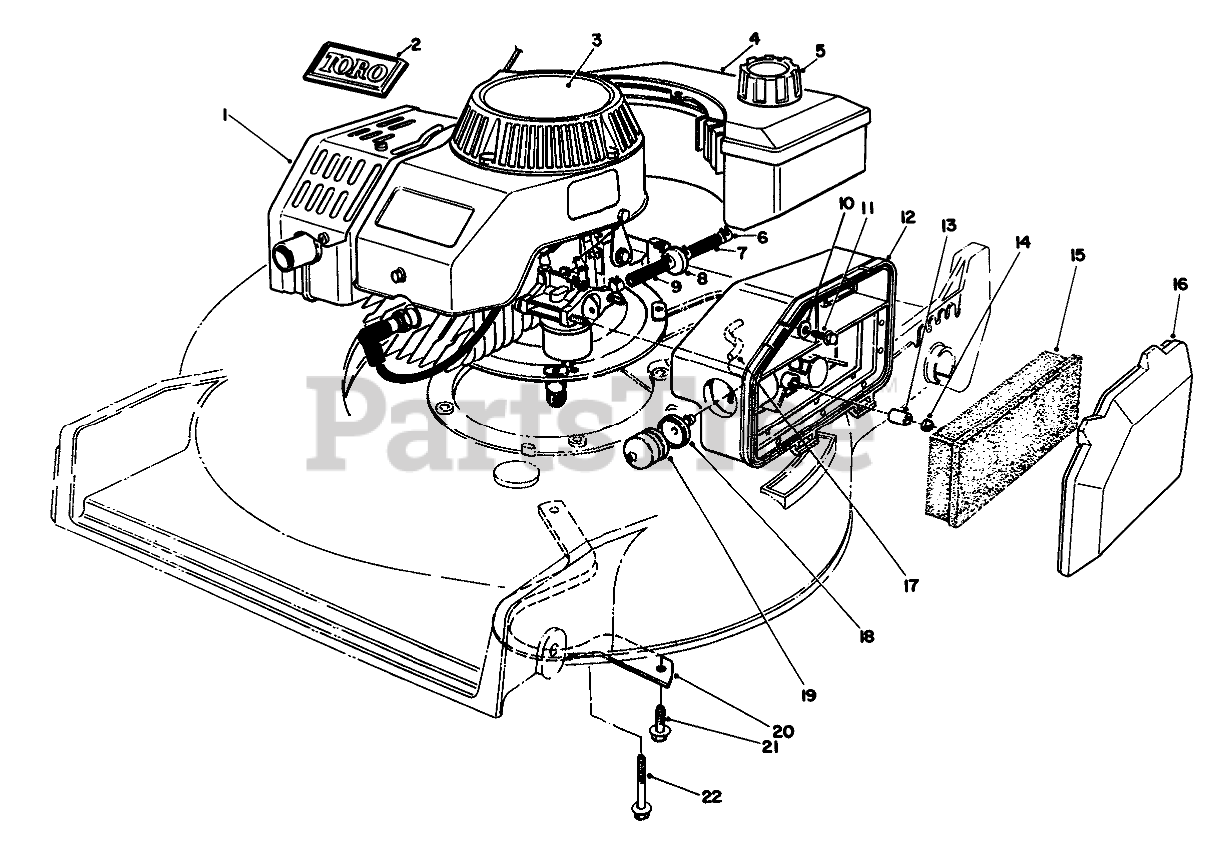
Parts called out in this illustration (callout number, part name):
1	Engine
2	TORO LOGO PLT
3	DECAL - 2 CYC RECOIL
4	Gas Tank Assembly
5	GAS CAP ASM
6	CLAMP-FUEL LINE
7	HOSE-FUEL
8	FILTER-FUEL
9	HOSE-FUEL
10	WASHER-FLAT
11	SCREW-HH
12	BODY-AIR CLEANER
13	SPACER
15	ELEMENT-AIR CLEANER
16	COVER-AIR CLEANER
17	HOSE-PRIMER
18	BODY-PRIMER
19	BULB-PRIMER
20	Guide-Belt
21	SCREW-HWHTF
22	SCREW-HHF
